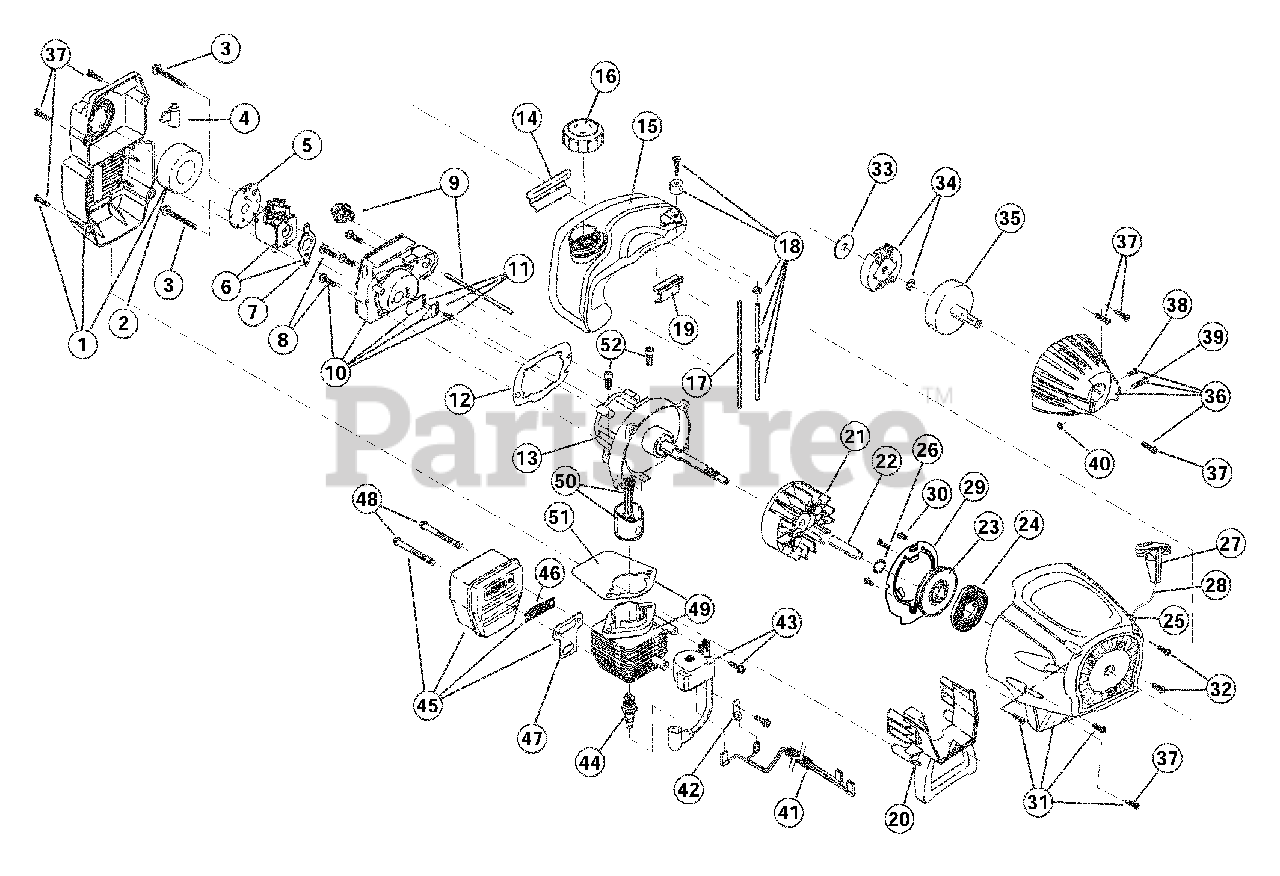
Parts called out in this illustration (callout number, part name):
1	Air Cleaner/Muffler Cover Assembly (includes 2 & 37)
2	Air Cleaner Filter
3	Carburetor Mounting Screw Assembly
4	Choke Extension
5	Choke Plate
6	Carburetor Assembly (includes 7 & 18)
7	Carburetor Gasket
8	Carb Mount Screw
9	Primer and Hose Assembly
10	Carb Mount Assembly (includes 8, 11 & 12)
11	Reed Assembly
12	Carburetor Mount Gasket
13	Crank Case Service Assembly (includes 8)
14	Rear Mounting Pad
15	Fuel Tank Assembly (includes 16-18)
16	Fuel Cap Assembly
17	Fuel Return Line
18	Fuel Line Assembly
19	Front Mounting Pad
20	Shroud Extension and Stand
21	Flywheel Assembly
23	Recoil Pulley Assembly
24	Recoil Spring
25	Rope Guide
26	Pulley Retainer
27	Pull Handle
29	Pressure Plate Assembly
30	Plate Screw
31	Starter Housing Assembly (includes 23-30, 32 & 37)
32	Housing Screw
33	Clutch Washer
34	Clutch Rotor Assembly
35	Clutch Drum Assembly
36	Clutch Cover Assembly (includes 37-40)
37	Cover Screw
38	Anti-Rotation Screw
39	Clamping Screw
40	Clamping Nut
41	Wire Leads and Sleeve
42	Ground Tab
43	Module Assembly
45	Muffler Assembly (includes 47, 48)
46	Spark Arrestor Screen
47	Exhaust Gasket
48	Muffler Mounting Bolt Assembly
49	Cylinder Assembly (includes 51, 52)
50	Piston and Rod Assembly
51	Cylinder Gasket
52	Cylinder Bolt
